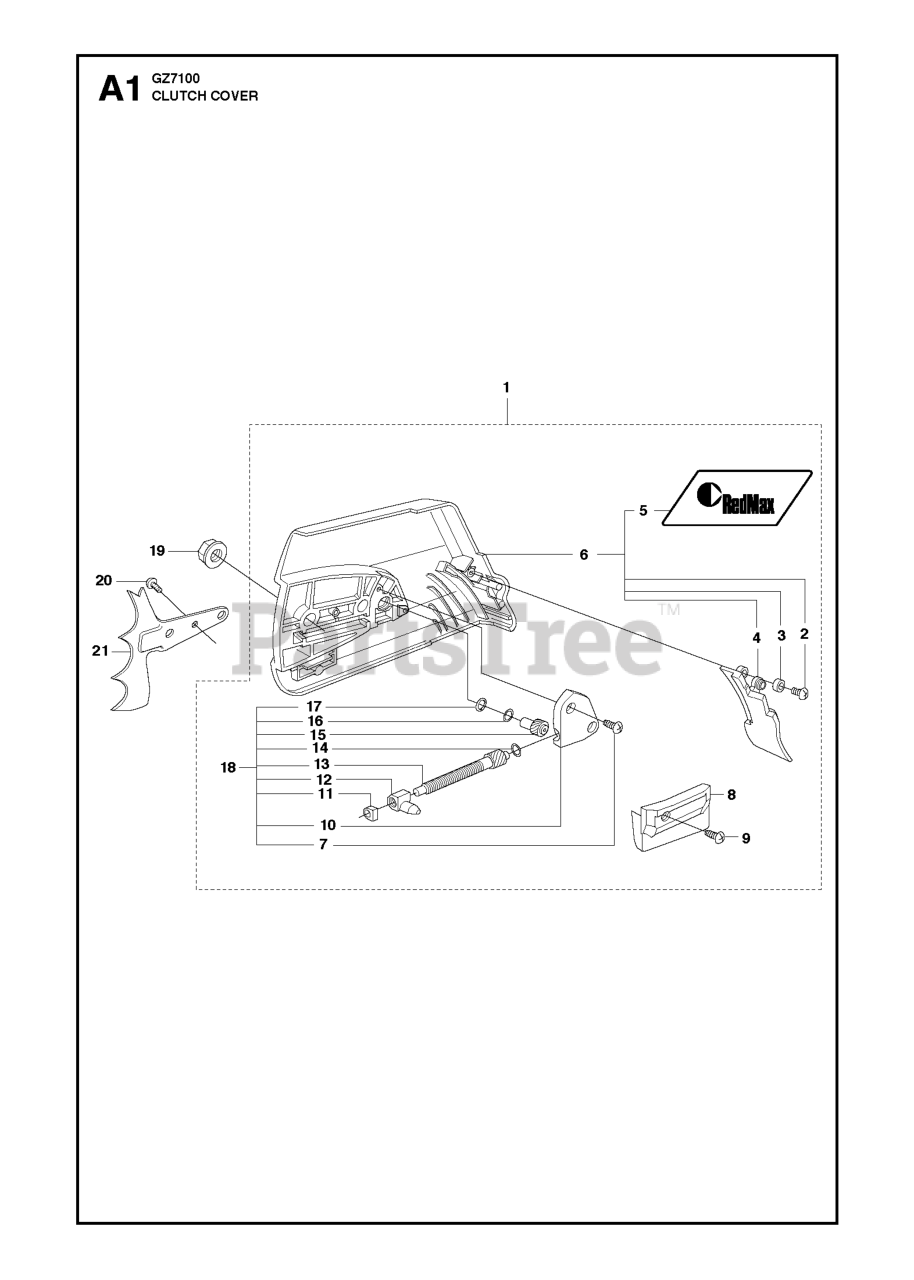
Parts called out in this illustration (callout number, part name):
1	CLUTCH COVER ASSY REDMAX
2	SCREW CITXPANT
3	WASHER
4	PROTECTOR
5	LABEL CLUTCH COVER REDMAX
6	CLUTCH COVER
7	SCREW CITXPANT
8	GUIDE
9	SCREW CITXPANT
10	COVER
11	SLEEVE
12	PAWL
13	WORM SCREW / ADJUSTER
14	WASHER
15	WORM WHEEL
16	WASHER
17	O-RING
18	KIT-CHAIN TENSIONER
19	NUT M8 FLANGE
20	SCREW CITXPANT
21	SPIKE OUTER
